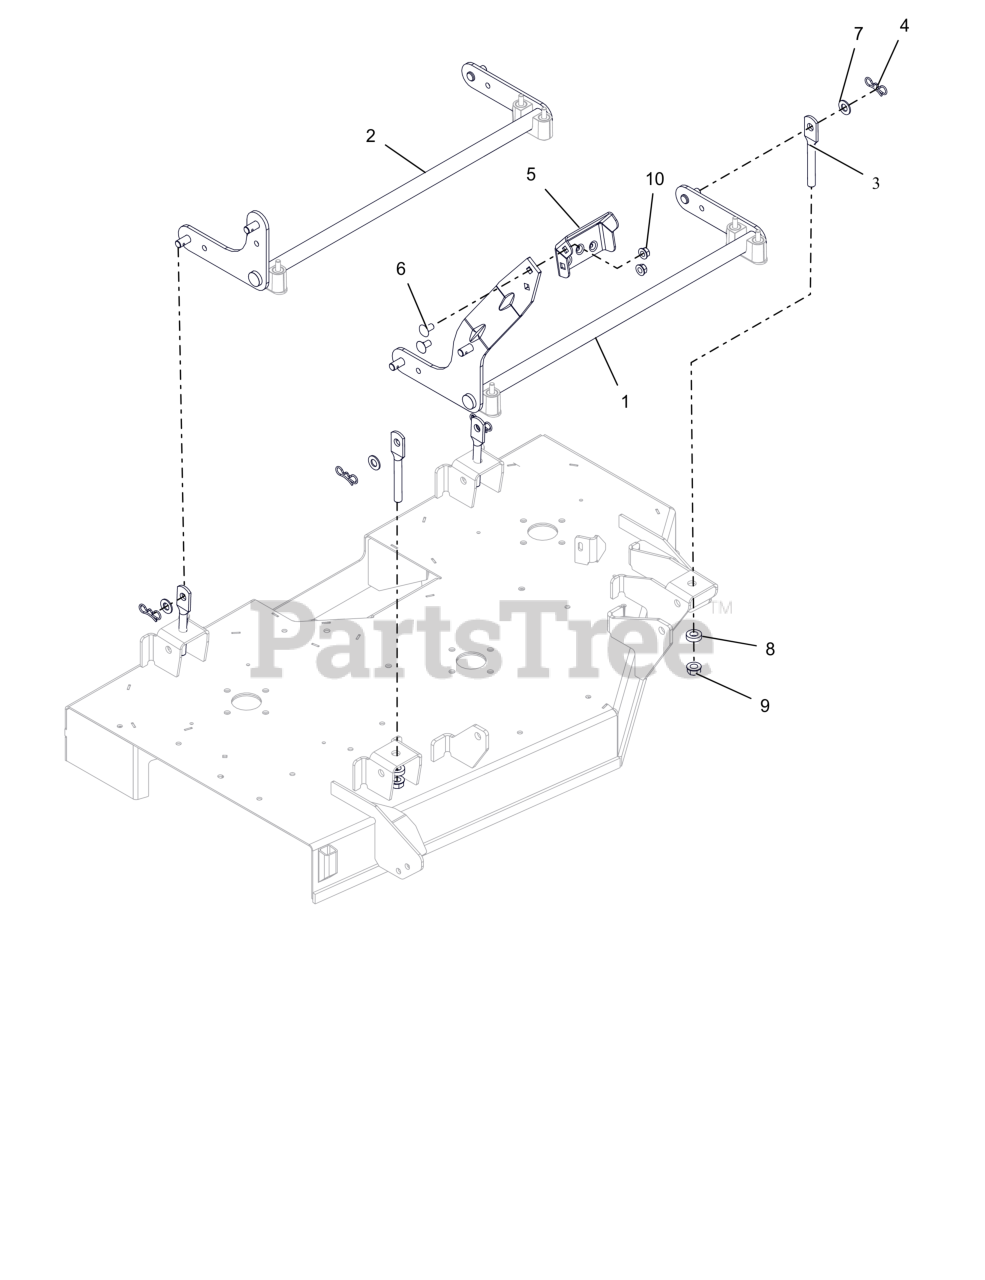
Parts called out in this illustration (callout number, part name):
1	WLDMT, FRONT DECK LIFT PIVOT
2	WLDMT, REAR DECK PIVOT
3	LINK, DECK (HOLE-LONG)
4	PIN, BOWTIE .091X1.875 ZCC
5	PEDAL, DECK LIFT (BOLT ON)
6	BTL,RHSSN .375-16 X 0.75 G5 FPB
7	WSHR-FL-NYL .518X1.000X.080
8	WSHR, RUBBER
9	NUT-LK-CTR-FLG .500-13 GG ZCC
10	NUT-LK-CTR-FLG .375-16 GF ZCC
